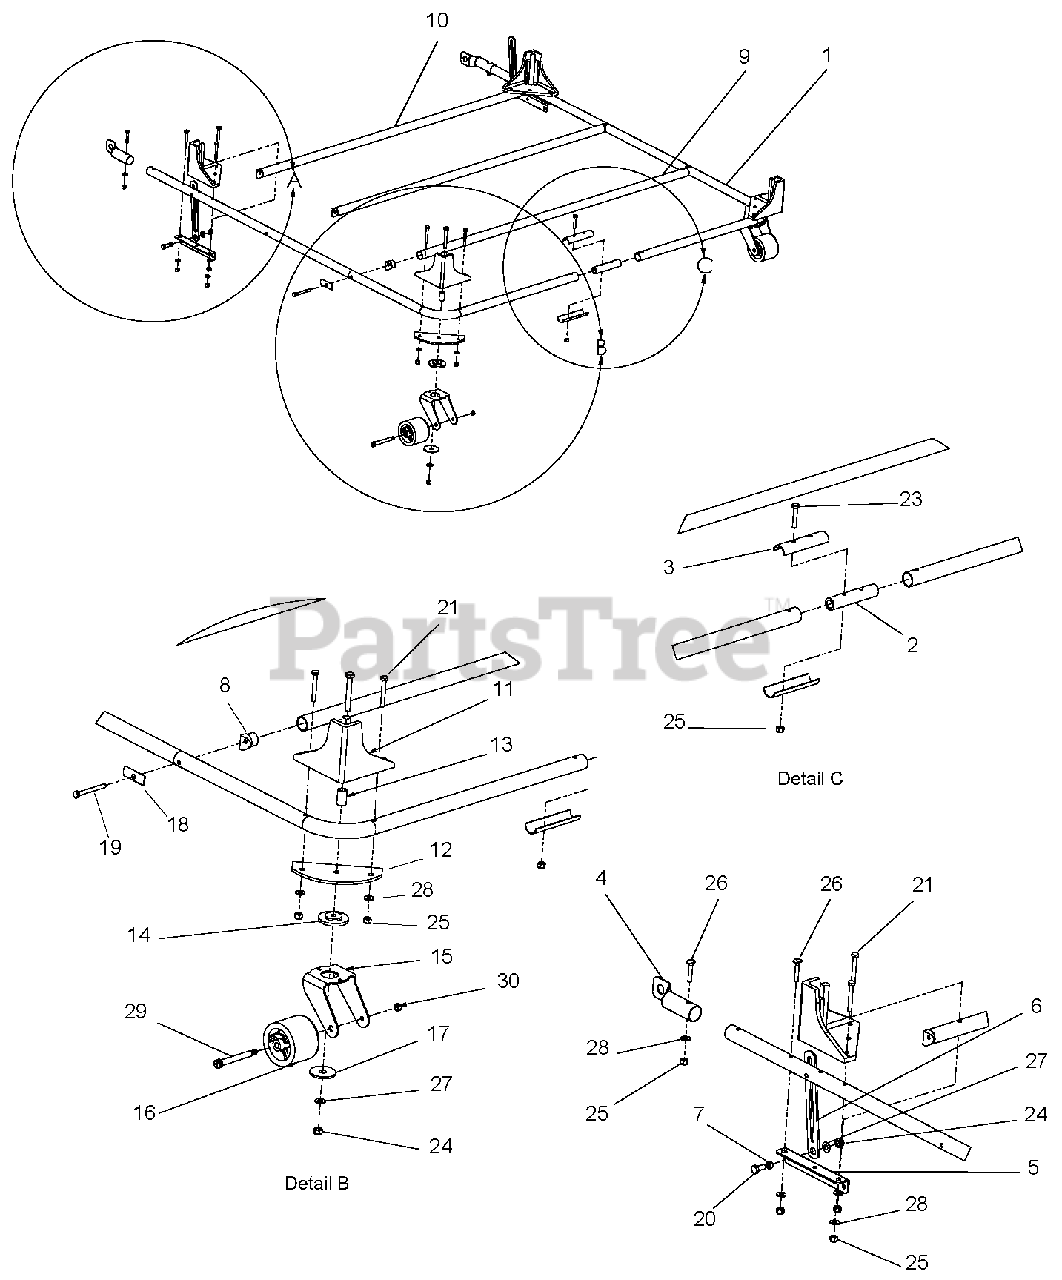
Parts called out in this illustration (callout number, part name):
1	Frame Side
2	Tube Insert
3	Clamp Half
4	End Cap, Tube
5	Angle Bracket
6	Bracket, Adjust
8	Tube Connector
9	Cross Brace, Mid/Back
10	Cross Brace, Forward
11	Corner Support
12	Caster Plate
15	Caster Fork
18	Bracket Clamp
19	Bolt, 1/4-20 x 2.50 Hex 5
20	Bolt, 5/16-18 x .75 Hex 5
21	Bolt, 1/4-20 x 2.00 Hex 5
22	Bolt, 5/16-18 x 2.50 Hex 5
23	Bolt, 1/4-20 x 1.50 Hex 5
24	Nut, 5/16-18 Nyloc
25	Nut, 1/4-20 Nyloc
26	Bolt, 1/4-20 x 1.50 Contour Hd.
27	Washer, .344 x .688 x .065 Flat Steel
28	Washer, .281 x .62 x .065 Flat Steel
29	Bolt, 3/8 x 2-3/4 Shoulder Socket
30	Nut, 1/4-20 Lock
